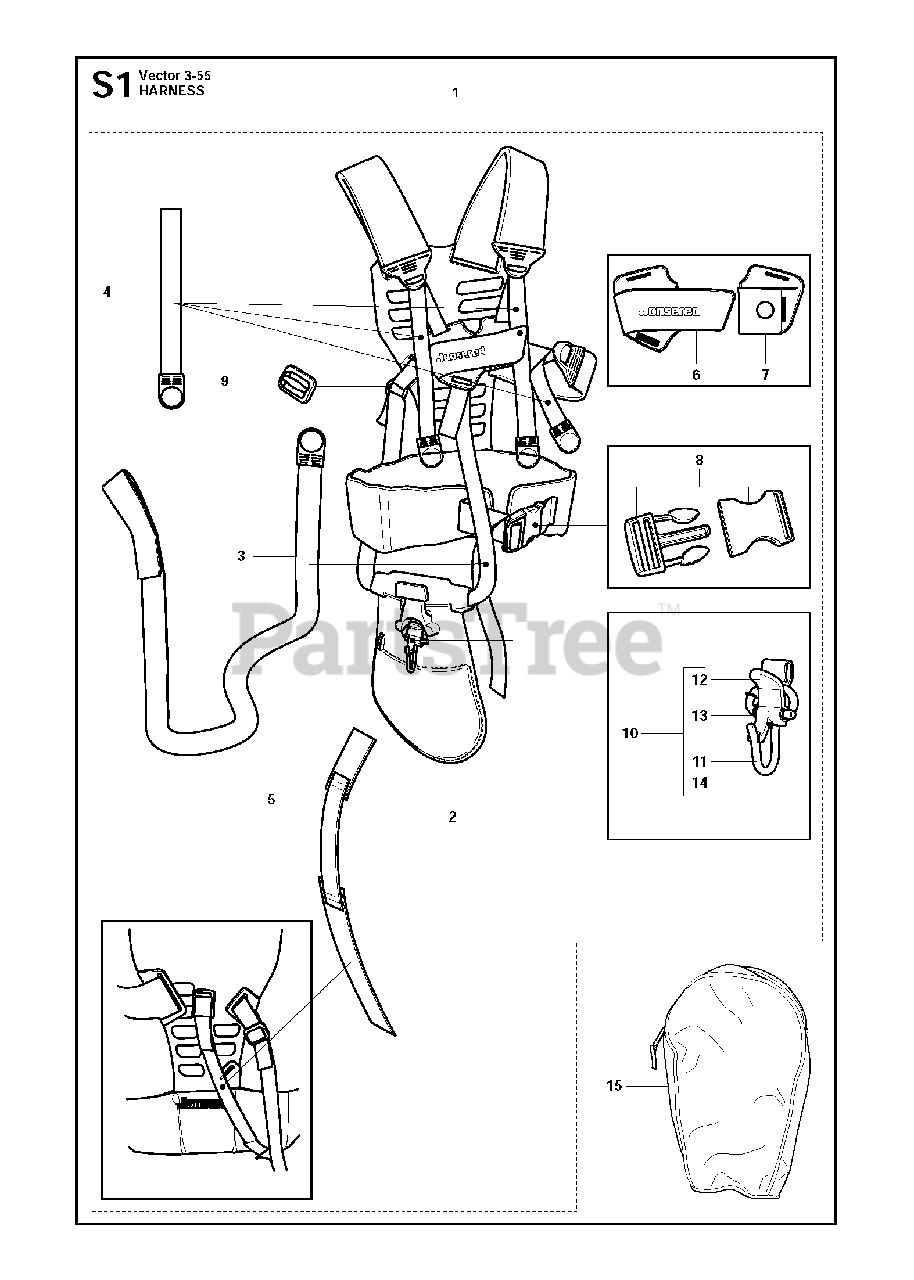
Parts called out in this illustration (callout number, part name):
4	BAND
6	FRONT PIECE
7	FRONT PIECE
8	BUCKLE
9	CLIP
10	WELT HOOK
11	HOOK
12	CATCH *
13	SPRING
14	E-RING 5
15	TOOL BAG
